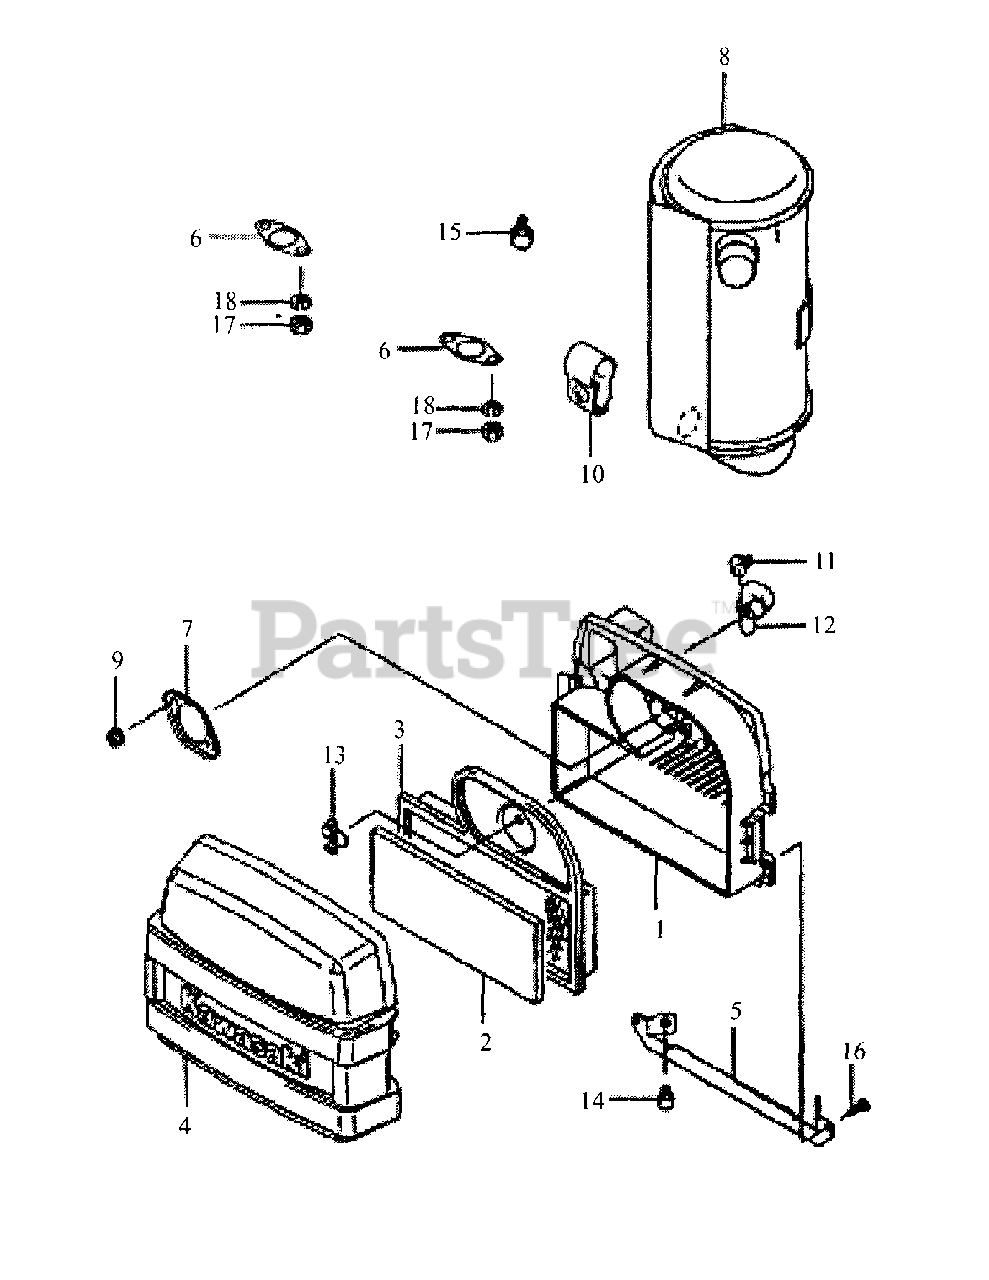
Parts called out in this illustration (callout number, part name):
1	Case, Air Filter
2	Element, Air Filter
3	Element, Air Filter
4	Case, Air Filter
6	Gasket, Muffler
14	Bolt, Flange
15	Bolt, Flange
16	Screw
17	Nut, Hex
18	Washer, Spring
